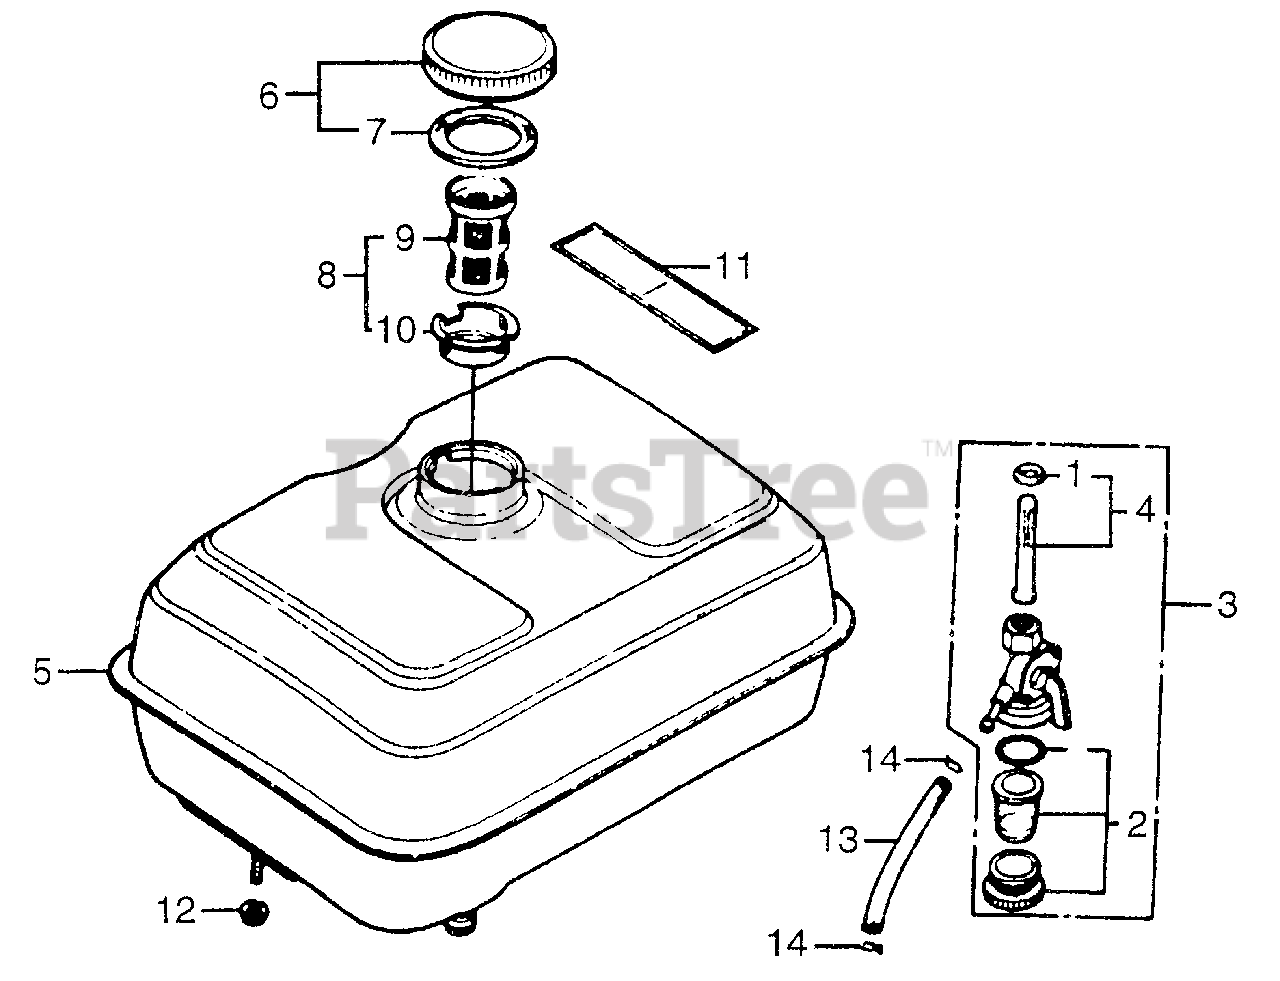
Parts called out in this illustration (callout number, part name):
1	GASKET SET, VALVE
2	CUP SET, FUEL STRAINER
3	PETCOCK ASSY.
4	SCREEN SET
5	TANK, FUEL *NH31* (MCKINLEY WHITE)
6	CAP, FUEL FILLER
7	GASKET, FUEL FILLER CAP
8	FILTER, FUEL
9	FILTER, FUEL
10	HOLDER, FUEL FILTER
11	MARK, CAUTION (ENGLISH/FRENCH)(SPANISH)
12	NUT, FLANGE (6MM)
13	BULK HOSE, FUEL (4.5X3000) (4.5X65)
14	CLIP, TUBE (B8)
